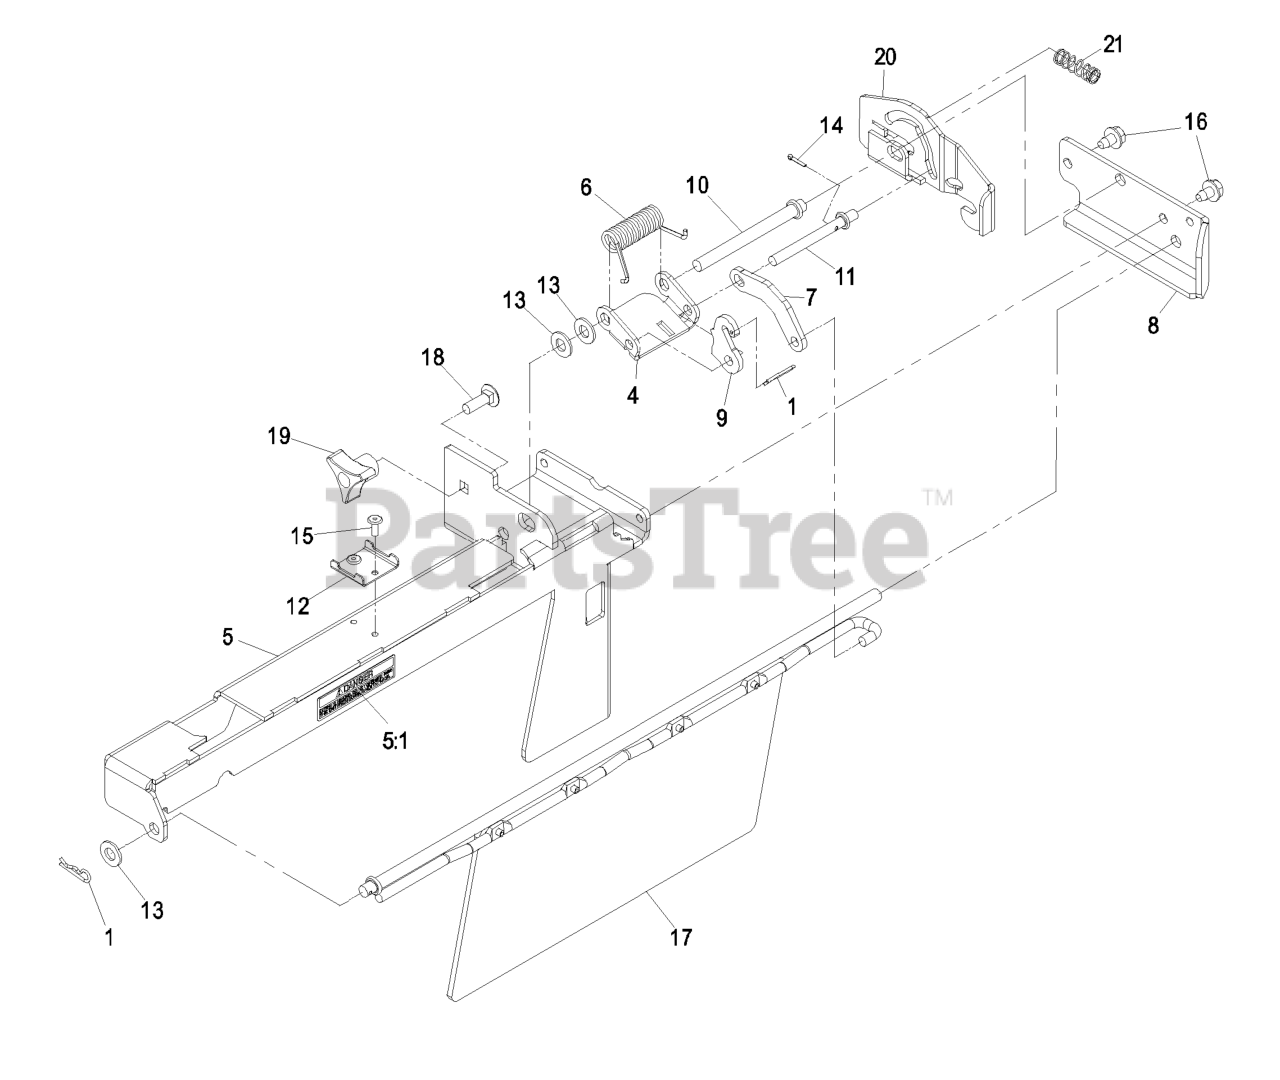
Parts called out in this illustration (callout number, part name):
1	PIN-COTTER
4	BRACKET,LINK PIVOT
5	GATE,LINK FRAME
5:1	DECAL-COVER, MISSING
6	SPRING,TORSION
7	LINK,GATE OCD
8	BRACKET,PIVOT SUPPORT
9	LINK,GATE LIFT
10	ROD,CONTROL PIVOT
11	ROD,CONTROL LINK
12	CHANNEL,LATCH CONTACT
13	WASHER-FLAT
14	PIN-COTTER
15	RIVET-BLIND
17	ASM,GATE OCD
18	BOLT-CARR
19	KNOB-3 PRONG
20	WLD,LATCH
